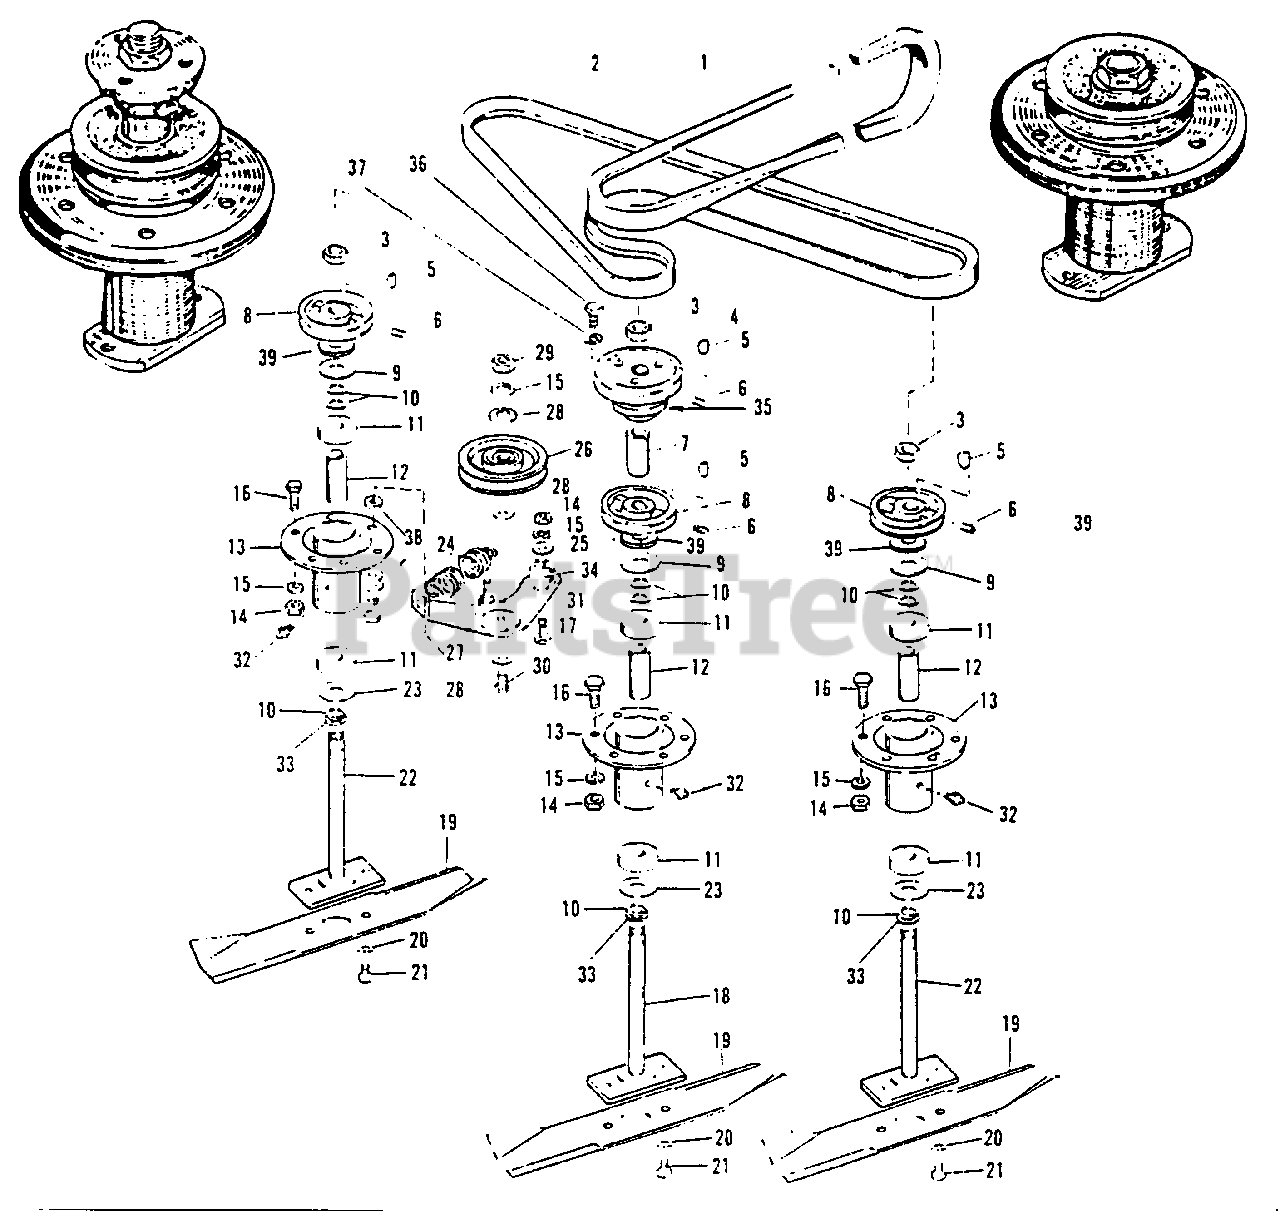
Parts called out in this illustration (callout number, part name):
1	Belt P.T.O.
2	Belt, "V" (Mower Spindle Drive)
3	Hex. Jam Lock Nut, 3/4"-16
5	Key, Woodruff, 61
6	Set Screw, 5/16"-18 x 3/8"
9	Backing Ring
13	Arbor Tube Assembly
14	Full Hex., Nut, 3/8"-16
15	Lock Washer, 3/8"
16	Hex. Cap Screw, 3/8"-16 x 3/4" lg.
17	Hex. Cap Screw, 3/8"-16 x 1 3/4" lg.
18	Arbor Crive Assembly
19	Knife Blade
20	Lock Washer, 3/8"
21	Hex. Hd. Capscrew, 3/8"-16 x 5/8"
22	Arbor Assembly
25	Plain Washer, 5/16"
26	Idler Pulley
28	Plain Washer, 5/16"
29	Full Lock Hex, Nut, 3/8"-16
31	Idler Lever Assembly
32	Grease Fitting
34	Race Inner Bearing
36	Screw, Cap-3/8"-24 x 1 3/4"
37	Washer, Lock-3/8"
38	Washer, 5/16"
